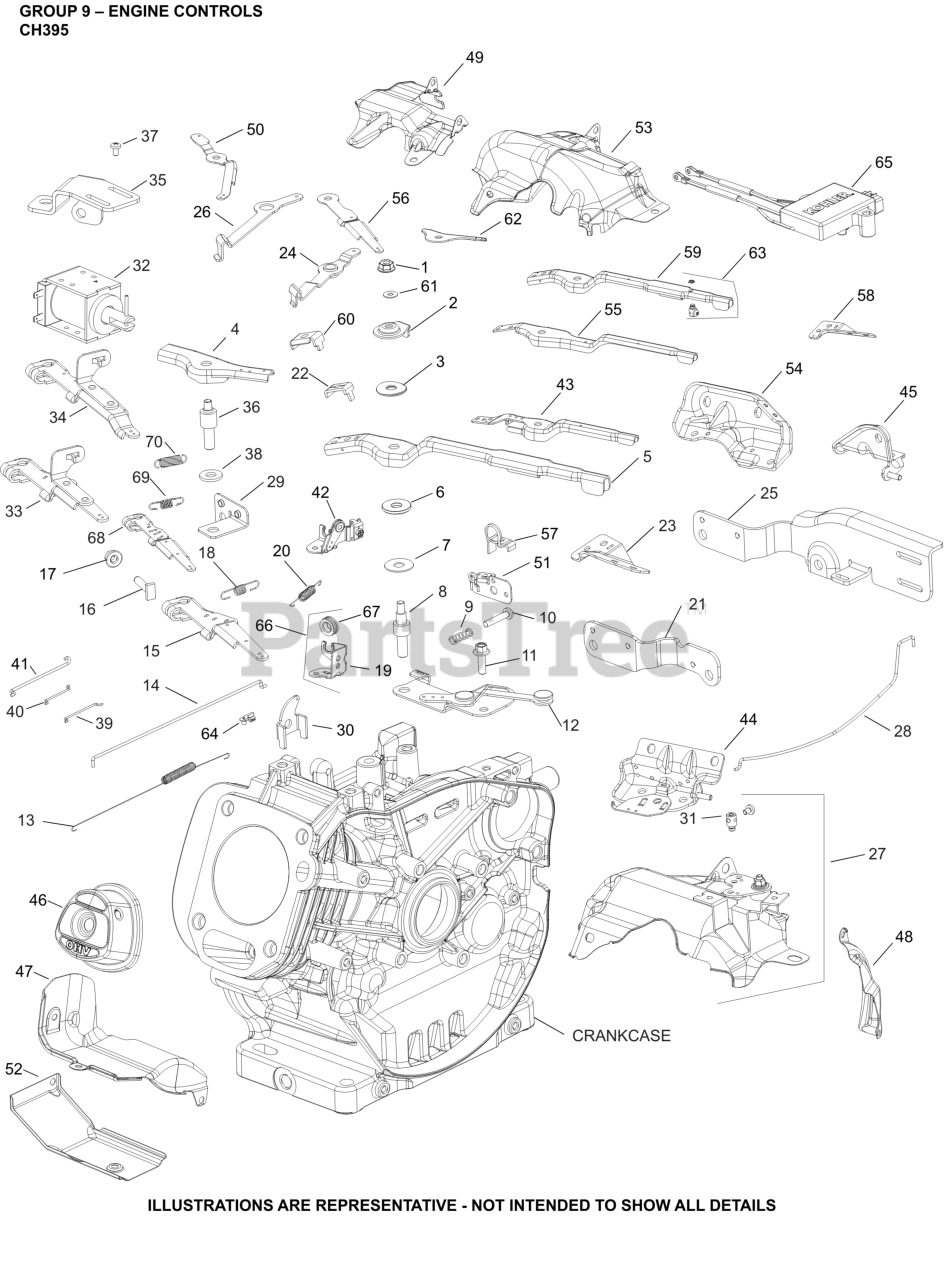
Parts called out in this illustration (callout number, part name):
9	SPRING, COMPRESSION
10	SCREW, SPEED ADJUSTING
11	SCREW, M6 X18
13	SPRING, LINKAGE
14	LINKAGE, GOVERNOR
15	KIT, GOVERNOR LEVER
16	SCREW, RECTANGLE HEAD (M6)
17	NUT, HEX FLANGE (M6) - USE 14 100 16-S
18	SPRING, GOVERNOR
29	BRACKET, CONTROL
32	KIT, SOLENOID IDLE
33	LEVER ASSEMBLY, GOV. IDLE PULL DOWN
34	LEVER ASSEMBLY, GOV. IDLE PULL DOWN
35	LEVER ASSEMBLY, GOV. IDLE PULL DOWN
36	STUD, CONTROL LEVER
37	SCREW, SET HEX FLANGE HEAD
